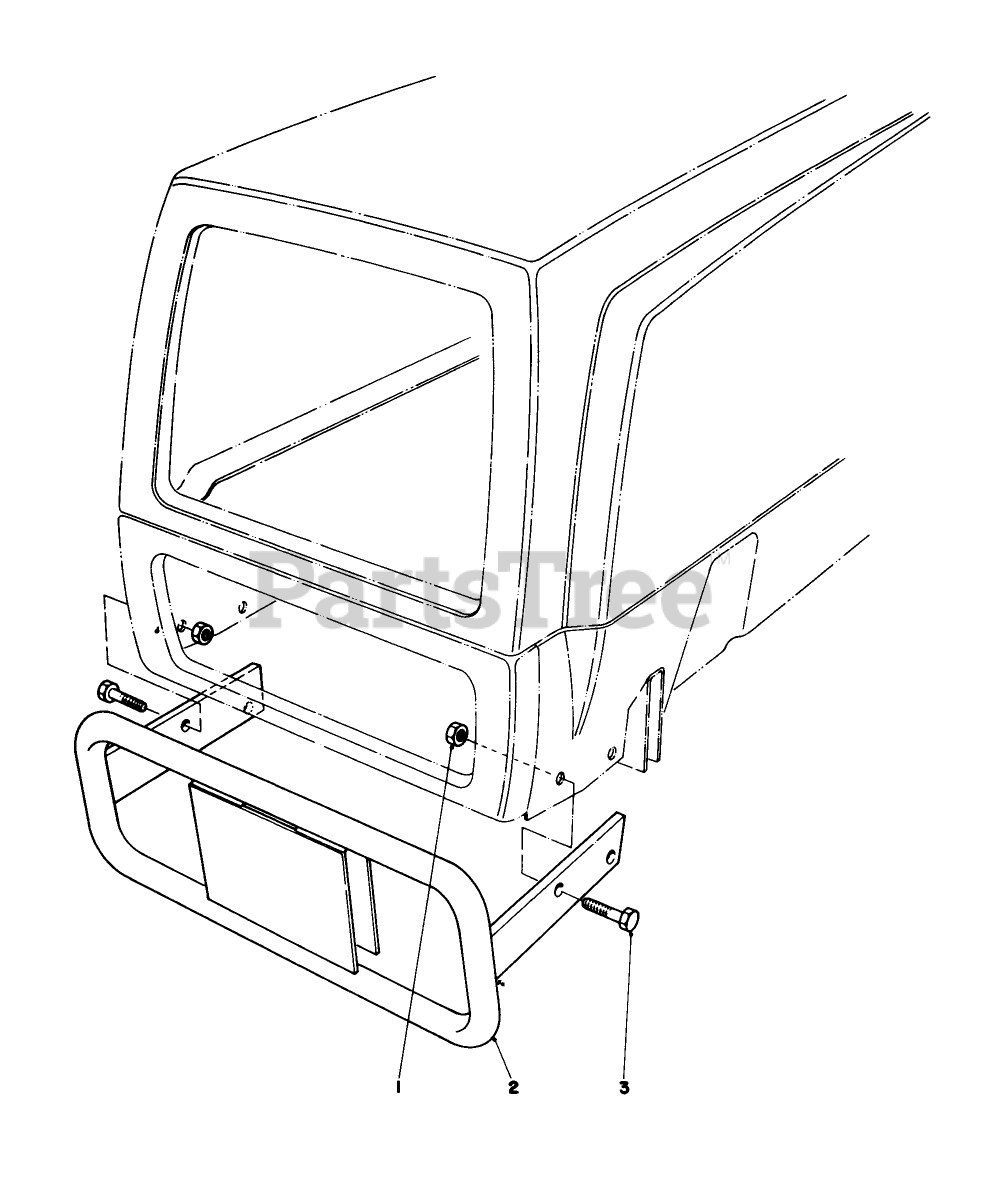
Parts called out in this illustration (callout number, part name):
1	NUT-LOCK, CONE
2	Bumper W.A.
3	SCREW-HH
